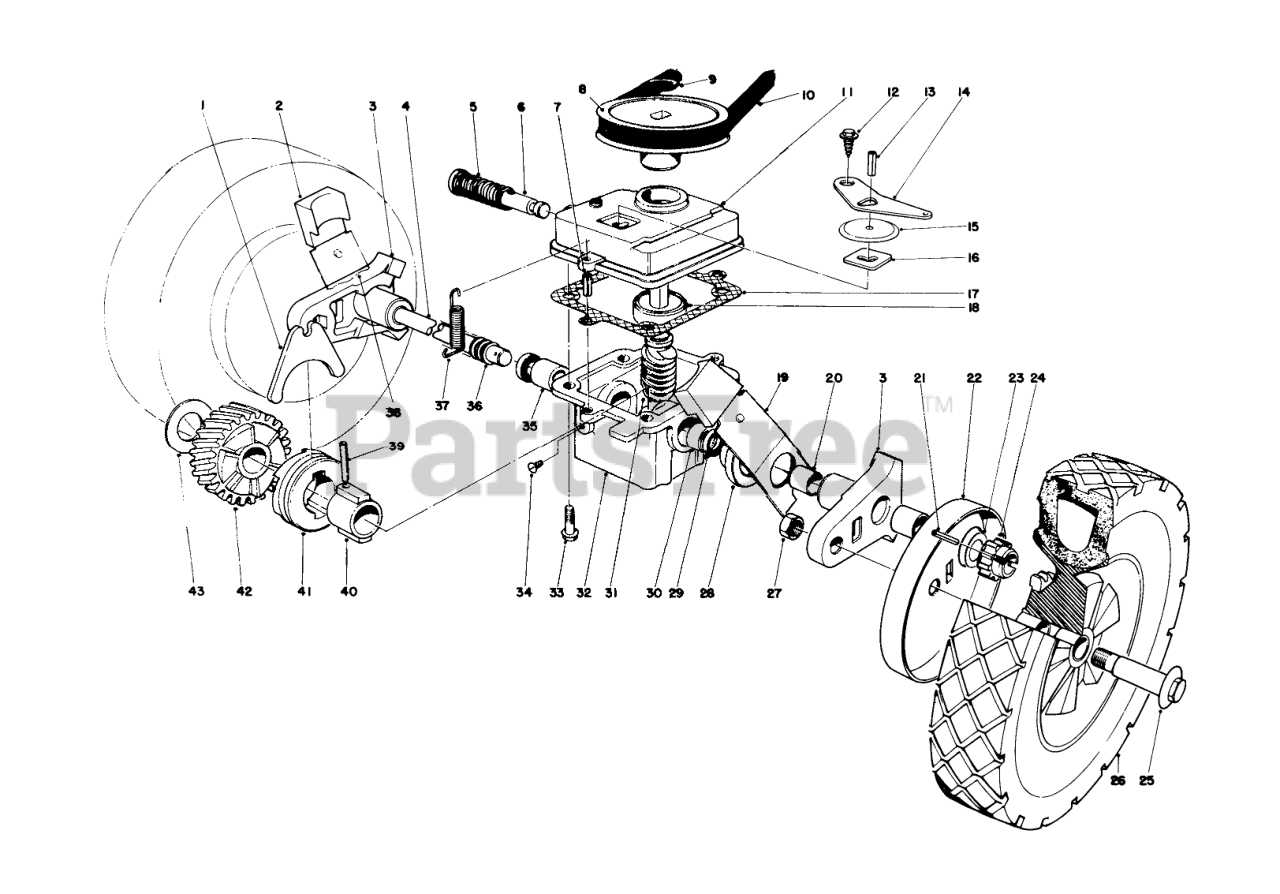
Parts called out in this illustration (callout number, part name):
1	SHIFTER FORK
2	KNOB-ARM
3	Pivot Arm (Incl. Ref. #20)
4	Drive Shaft
5	SPRING
6	Shift Rod
7	3/16 X 1/2 ROLL PIN
8	PULLEY
9	PUSH-ON 93-3236
10	V BELT
11	GEAR CASE COVER
12	Screw
13	PIN-ROLL
14	SHIFTER ARM
15	TRANS DUST COVER
16	LATCH PLATE
17	GASKET
18	Bearing
19	SPRING ARM ASM SP LH
20	BUSHING
21	PIN-GROOVED
22	WHEEL COVER
23	WASHER-THRUST
24	Pinion
25	BOLT-WHEEL
26	Wheel & Tire Assembly
27	Nut
28	End Cap
29	Seal
30	Bushing
31	WORM SHAFT
32	Gear Case (Incl. Ref. #29-30 & 35)
33	Screw
34	NYLON SCREW
35	Bushing
36	COVER-SHAFT, DRIVE
37	TENSION SPRING
38	SPRING ARM ASM SP RH
39	COIL PIN
40	SLEEVE
41	CLUTCH JAW
43	THRUST WASHER
